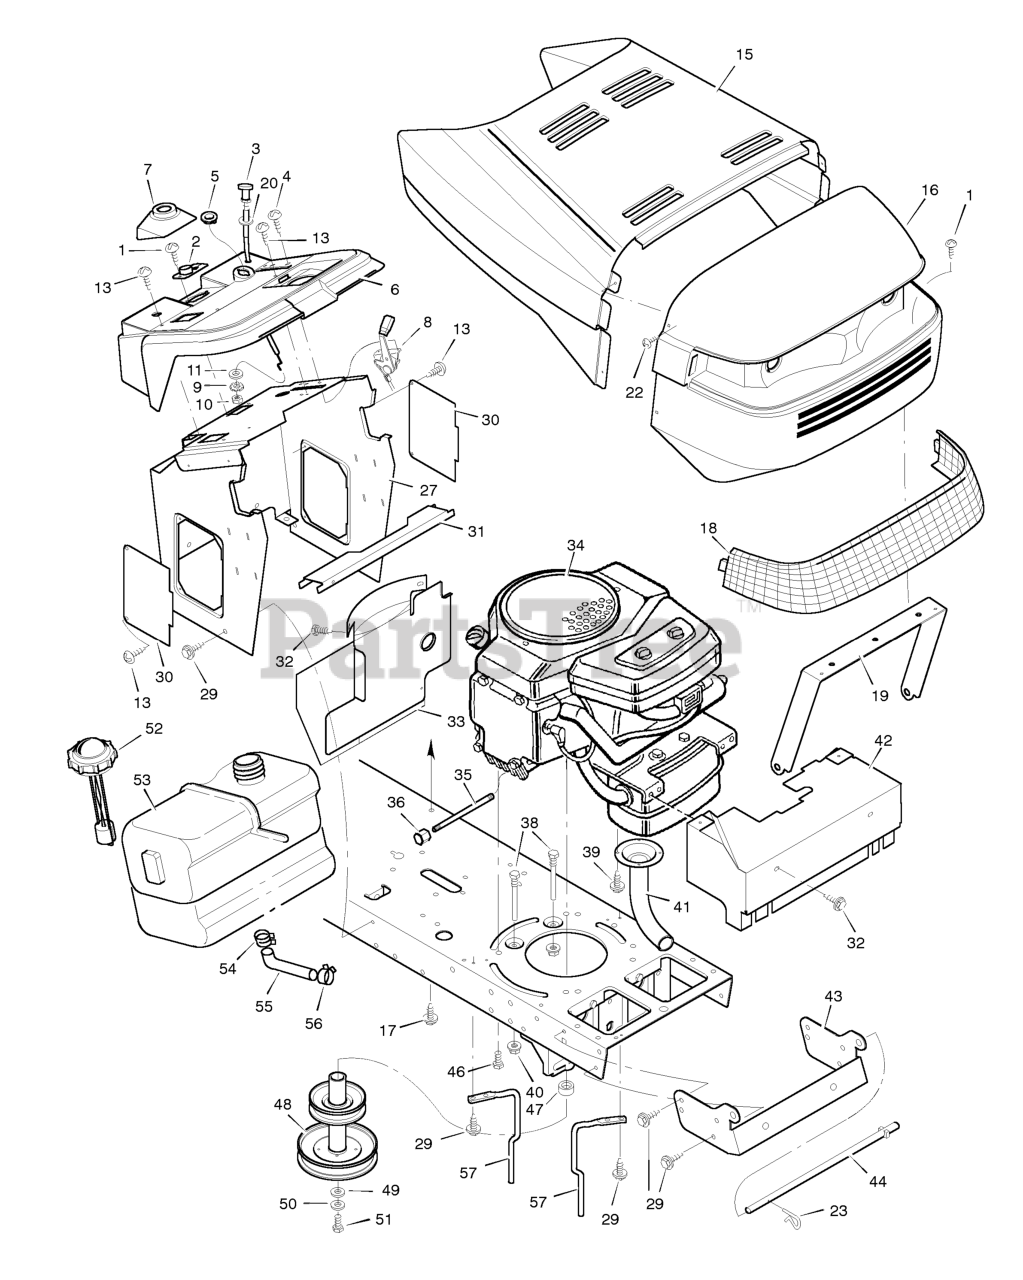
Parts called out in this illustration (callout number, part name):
2	Bearing, Steering Post
3	Cable, Choke
5	Bushing
7	Support, Bellows
8	Throttle Control
9	Lockwasher
10	Nut, Hex
11	Washer
13	Screw
15	Hood
16	Grille
19	Brace, Grille
20	Washer
23	Pin, Hair
27	Console Assembly
30	Panel, Side Access
31	Support, Fuel Tank
32	Screw
33	Baffle, Rear Heat
34	Engine *
35	Oil Drain Extension
36	Oil Drain Cap
38	Guide, Belt
40	Locknut, Flange
41	Pipe, Exhaust
42	Shield, Heat
43	Support, Grille
44	Rod, Pivot
46	Bolt, Hex
47	Spacer, Engine
48	Pulley Assembly, Stack
50	Lockwasher
51	Bolt, Hex
52	Cap, Fuel
53	Fuel Tank
54	Clamp, Hose
55	Fuel Line
56	Clamp, Hose
57	Guide, Belt
